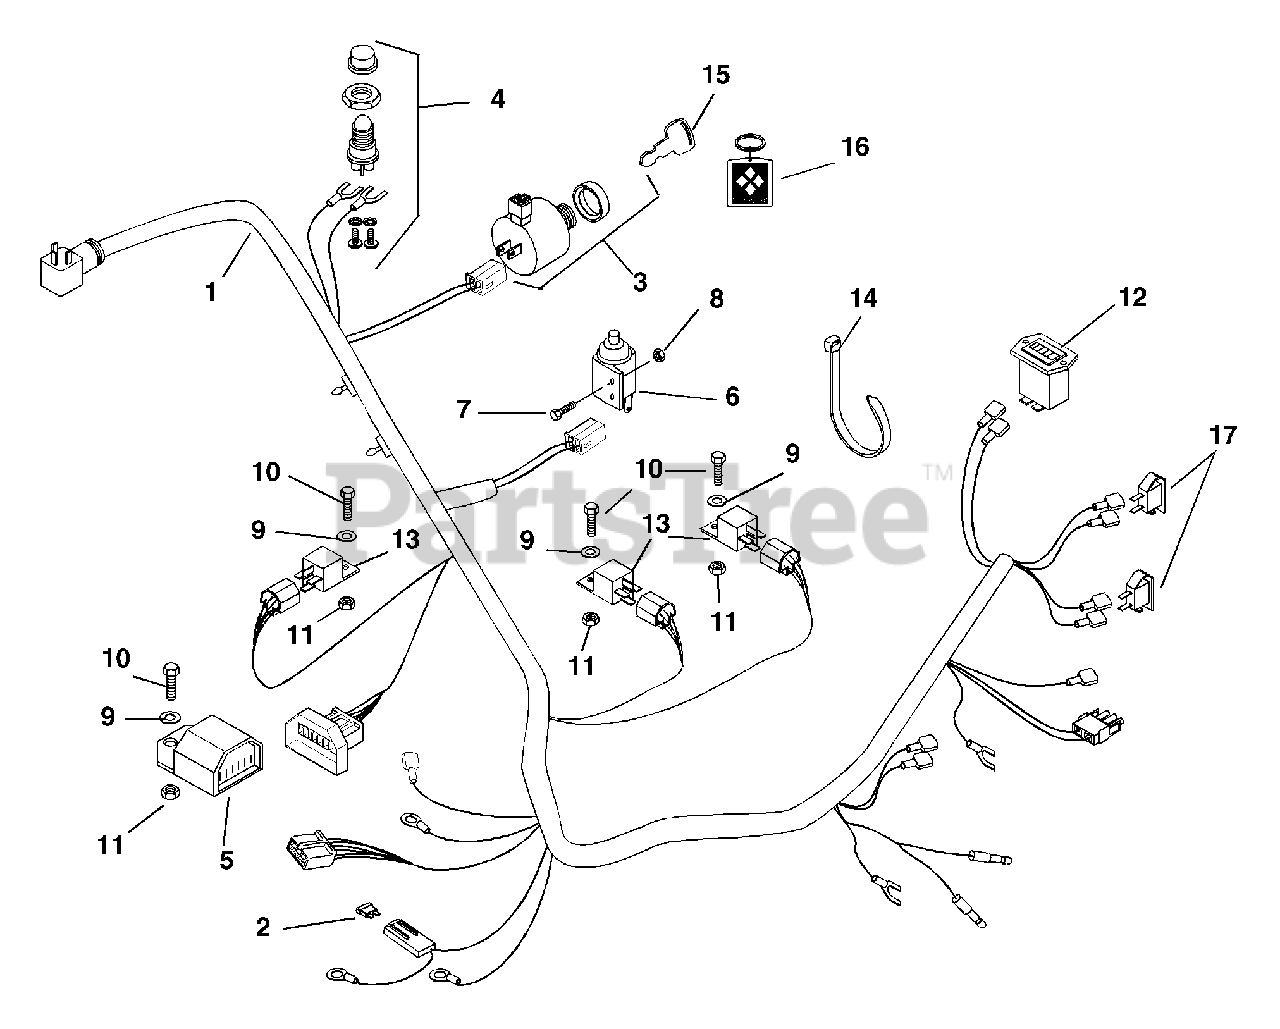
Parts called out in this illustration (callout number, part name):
1	Harness,Wiring 20HP Kubota
2	Fuse-30 Amp
3	Switch-Ignition-Kubota
4	Switch
5	Module-Interlock Delay
6	Switch-Operator Presence
7	Bolt-Hex M5-.8 x 16
8	Nut-Locking-Nylon M5-.8
9	Washer-Flat-Steel .194 x .492 x .047
10	Bolt-Hex M5 x .80 x 16
11	Nut-Locking-Nylon M5 x .80
12	Meter-Hour
13	Relay
14	Cable-Tie Large 5-1/2
15	Key, Ignition
16	Key Chain
17	Light, Indicator
